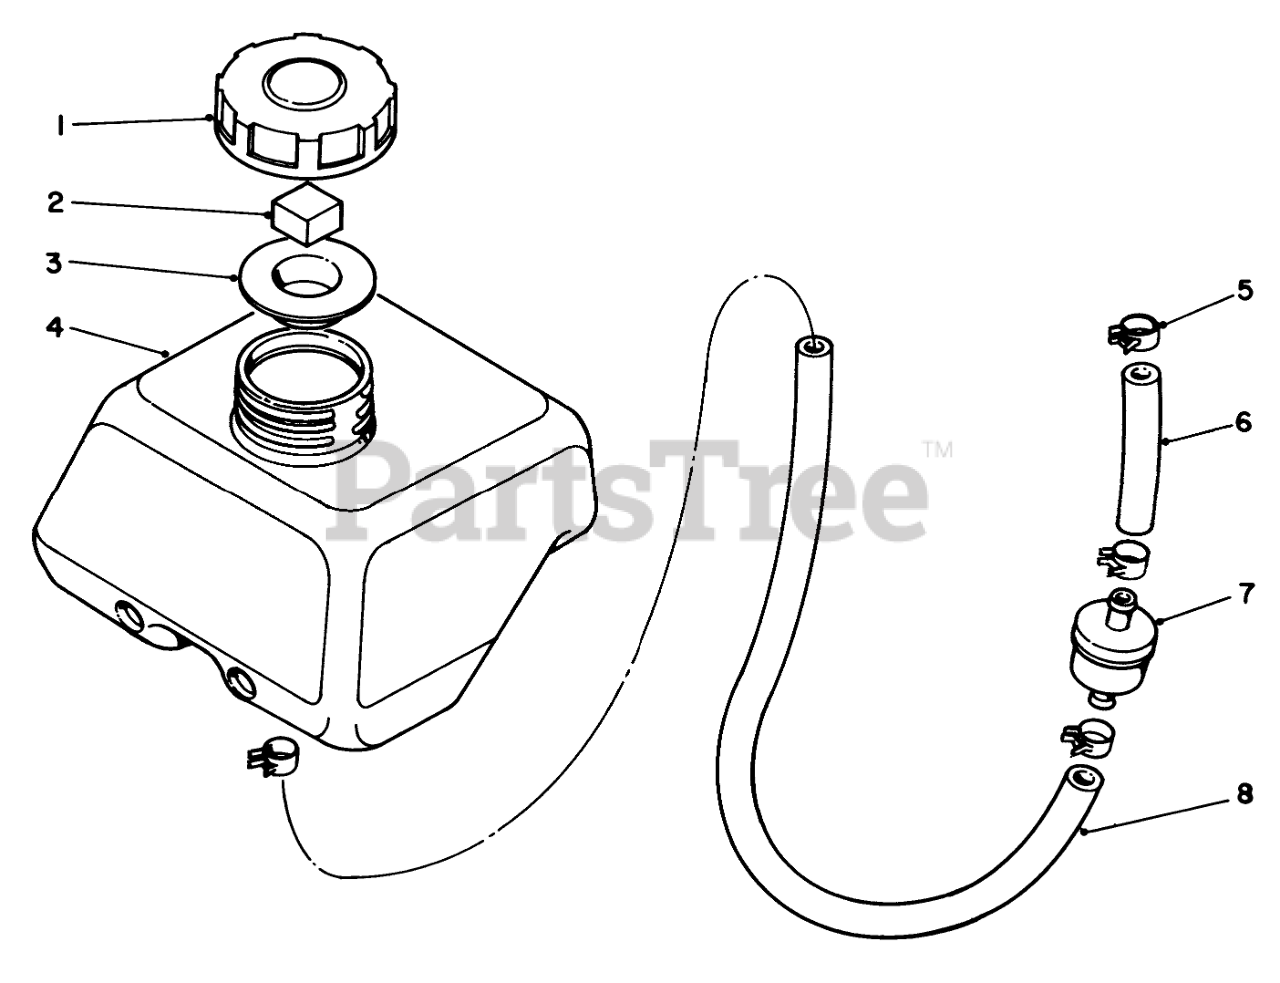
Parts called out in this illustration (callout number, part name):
1	Fuel Cap Assembly (Incl. Ref. #2 & 3)
2	Gasket-Inner
3	Gasket-Outer
4	Tank-Fuel
7	FUEL FILTER
